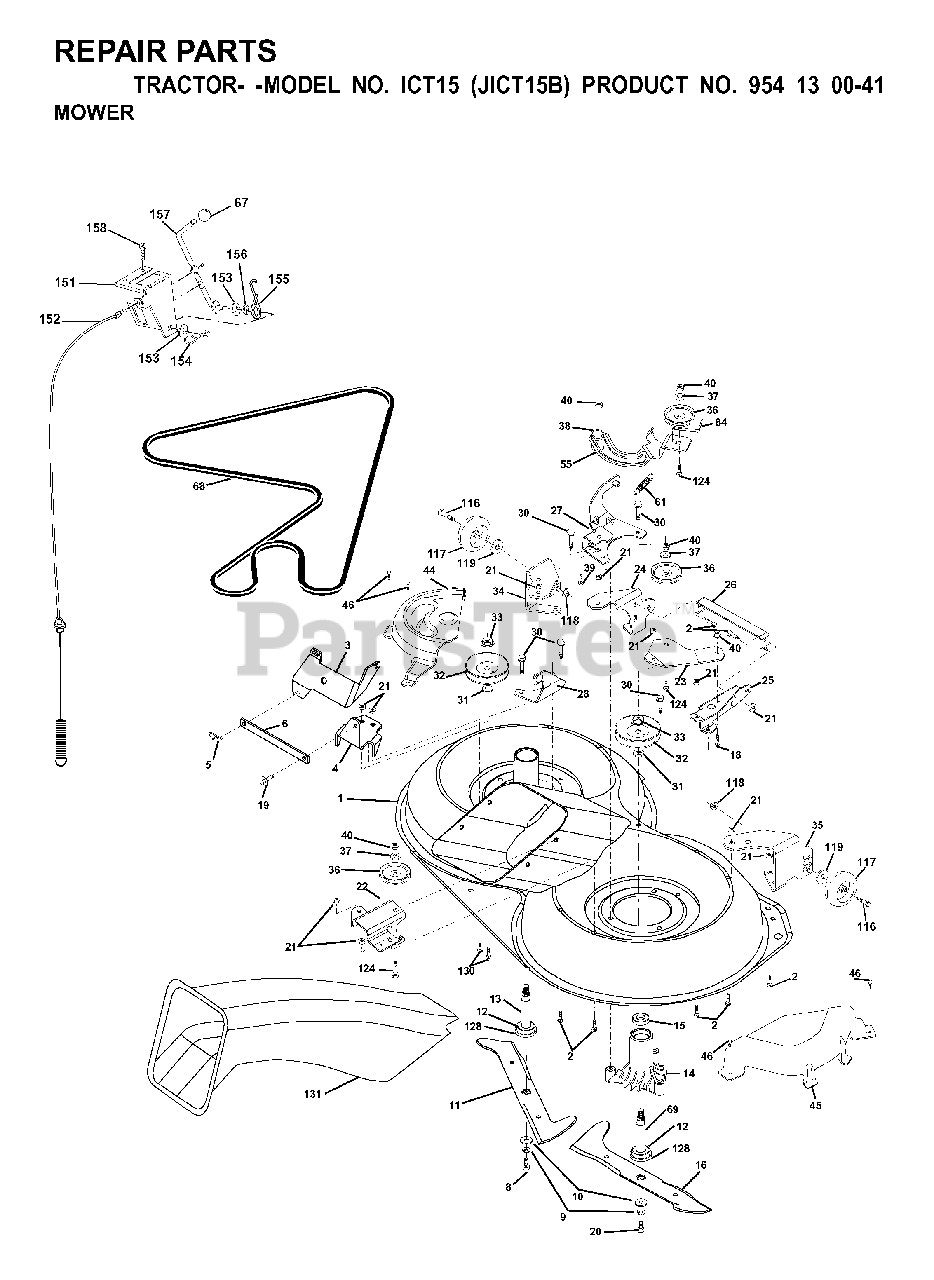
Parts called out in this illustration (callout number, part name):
2	BOLT
3	BRACKET
5	RETAINER-SPRNG RB
6	BAR SWAY
8	BLADE BOLT
9	LOCKWASHER
10	WASHER.BLADE
11	BLADE - LH (CTH150)
12	BEARING
13	SHAFT ASM VENT
14	HSG MANDREL
16	BLADE - RH (CTH150)
19	BOLT SHD 5/16-18
21	LOCKNUT
22	BRACKET
23	BRACKET
26	BRACE
27	BRACKET
30	SCREW THDROL ROLLING WASHER HD
31	WASHER
32	PULLEY/MANDREL
33	NUT
34	BRACKET
36	PULLEY.IDLER.4.25
40	LOCKNUT
45	MANDREL COVER RH
46	SCREW.1/4-20X5/8
55	ARM IDLER
61	SPRING.TENSION.BELT
67	KNOB T (3/8 HOLE)
68	HEX-BELT 107 MOWER
69	SHAFT.ASM.W/LWR.BRG.RH.THREAD
84	KEEPER, BELT IDLER
116	BOLT, SHOULDER
117	WHEEL GAGE DONUT
118	LOCKNUT
119	WASHER
124	BOLT.3/8-16X1.50
128	WASHER FELT
131	CHUTE BAGGER
151	BRACKET, CLUTCH CABLE
153	WASHER FLAT 3/8"
154	SPRING RETAINER
155	SPRING RETENTION LEVER
156	SPACER CLUTCH CABLE
157	ROD CLUTCH CABLE 3/8"
158	SCREW LT
